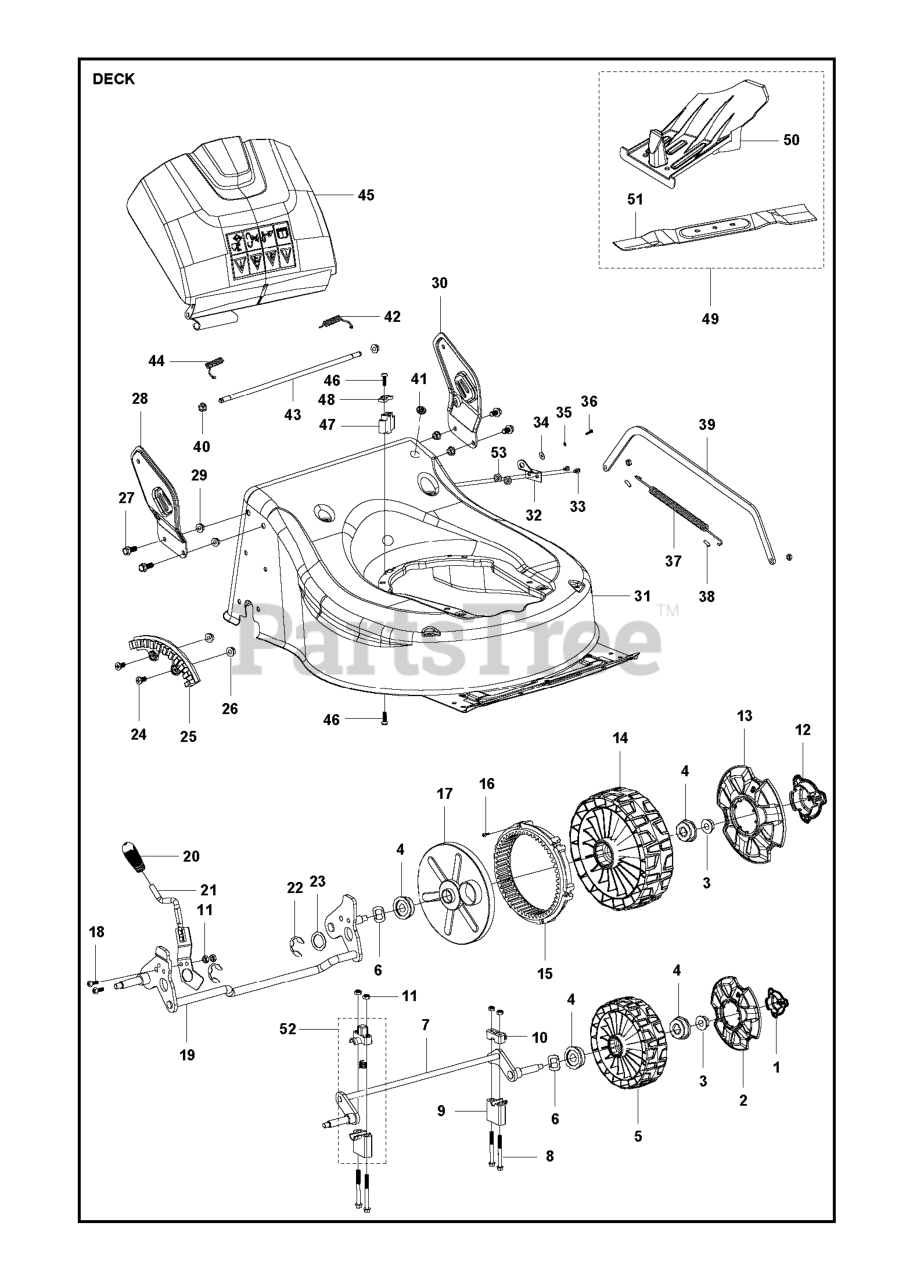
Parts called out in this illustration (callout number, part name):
1	WHEEL COVER 6" #25340700101
2	COVER 7 WHEEL COVER
3	LOCKING BOLT M8,GB6187.1 #2680
5	WHEEL ASSY 7 WHEEL
6	WASHER Ï?12 #26800706202
7	FRONT AXLE ASSY
11	LOCKING BOLT M6,GB889.1 #26800
12	WHEEL COVER 8" #25341000101
13	WHEEL COVER 8" #25341100101
14	WHEEL 8" #25341200101
15	GEAR WHEEL #25229900201
17	COVER #25342800101
18	WASHER M6*14 #26800203001
19	SHAFT ASSY REAR #26300298401
20	KNOB HEIGHT ADJUSTMENT #25341
21	HANDLE ASSY
22	WASHER Ï?19*1.5,GB896 #2680090
23	WASHER #26300107601
25	SEGMENT #25214200102
27	BOLT M8*16 #26800606401
28	BRACKET RH
30	BRACKET LEFT
31	CHASSIS # 21062009970013A
32	GUIDE PLATE # 26300360001
33	BOLT # 26800611201
34	WASHER # A26800700901
35	SPRING WASHER # A26800800402
36	SCREW TAPPING # A26800105402
37	SPRING #26801103903
38	TUBING #29000300101
39	CONNECTING ROD
40	LOCK NUT M6,GB/T6187.1-2000 #2
41	COVER #25217800104
42	BRACKET #26801125401
44	SPRING #26801125501
45	FLAP REAR # 2100X03758
47	HOLDER # 2109100010N
50	PLUG MULCHING
51	BLADE 26300349801
53	NUT
